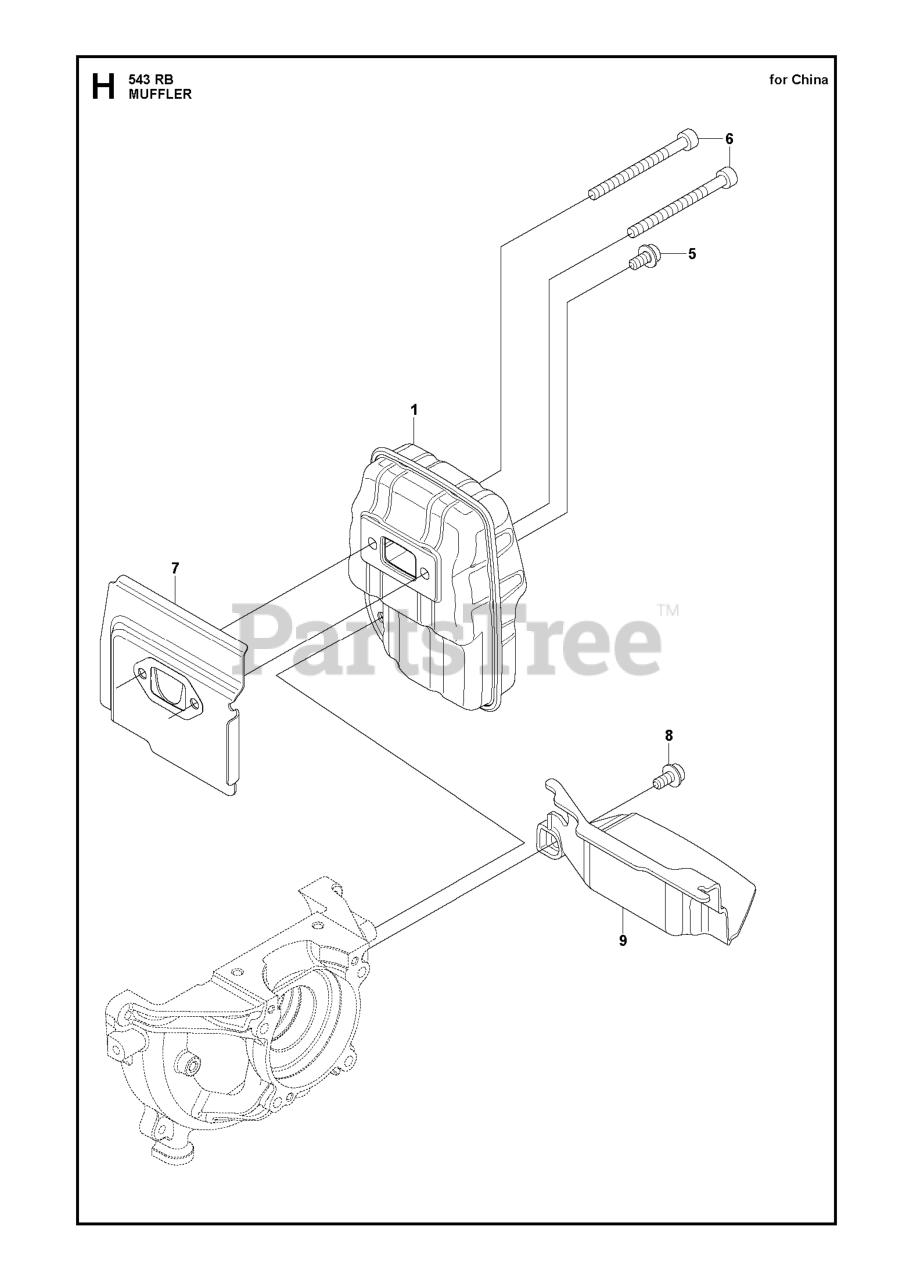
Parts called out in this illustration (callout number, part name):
5	BOLT (RPLS T495051010-11)
6	BOLT
7	GASKET
8	BOLT (RPLS T495051010-11)
